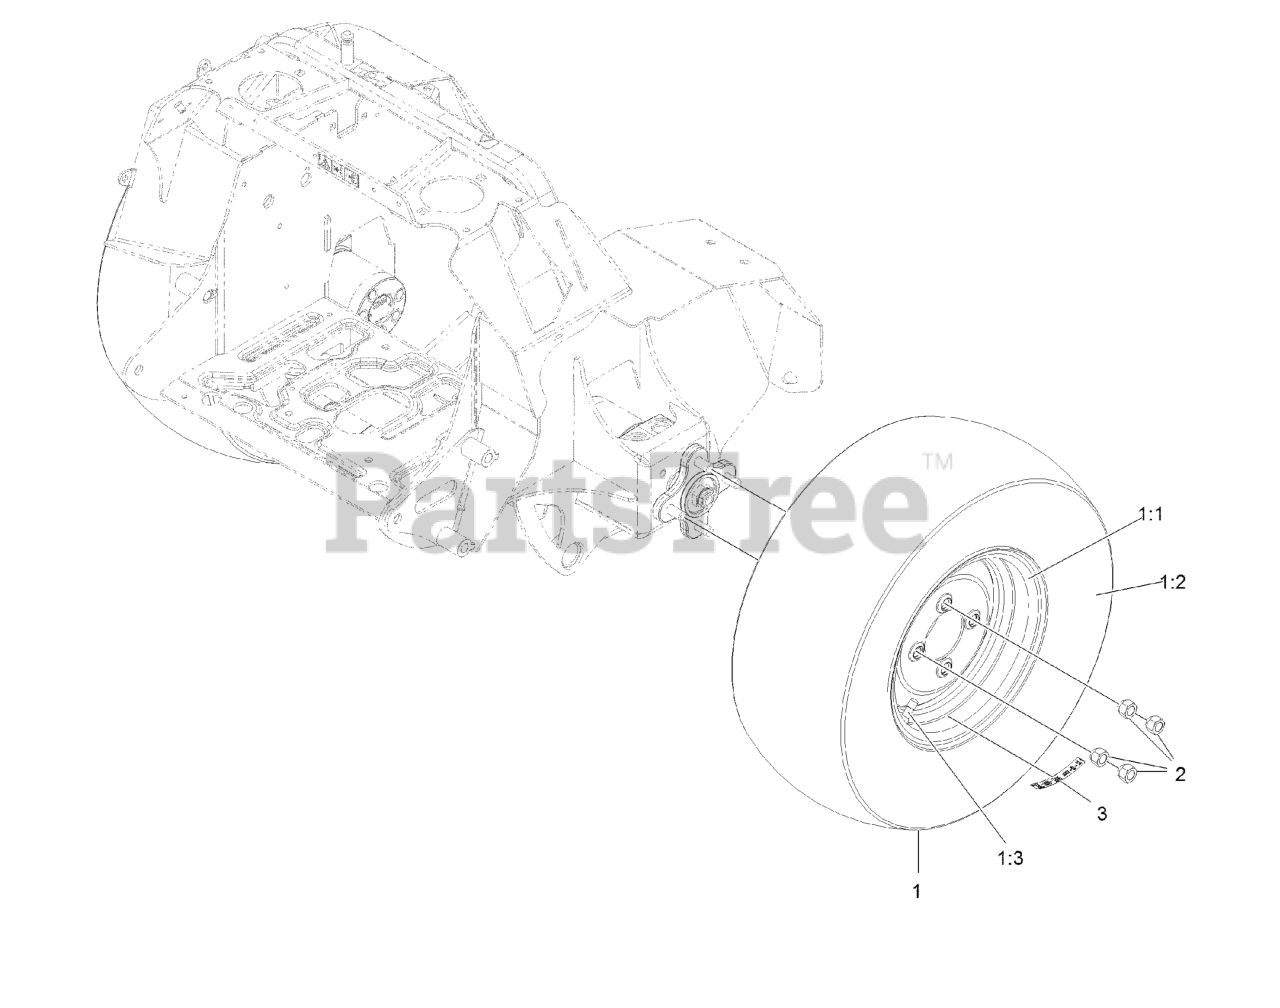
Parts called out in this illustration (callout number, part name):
1	ASM-WHL TIRE
1:1	WHEEL 10 X 6 WHT
1:2	TIRE-21X8.5-10
1:3	Stem-Valve
2	NUT-LUG
3	DECAL-TORQUE WHEEL LUG-HU
